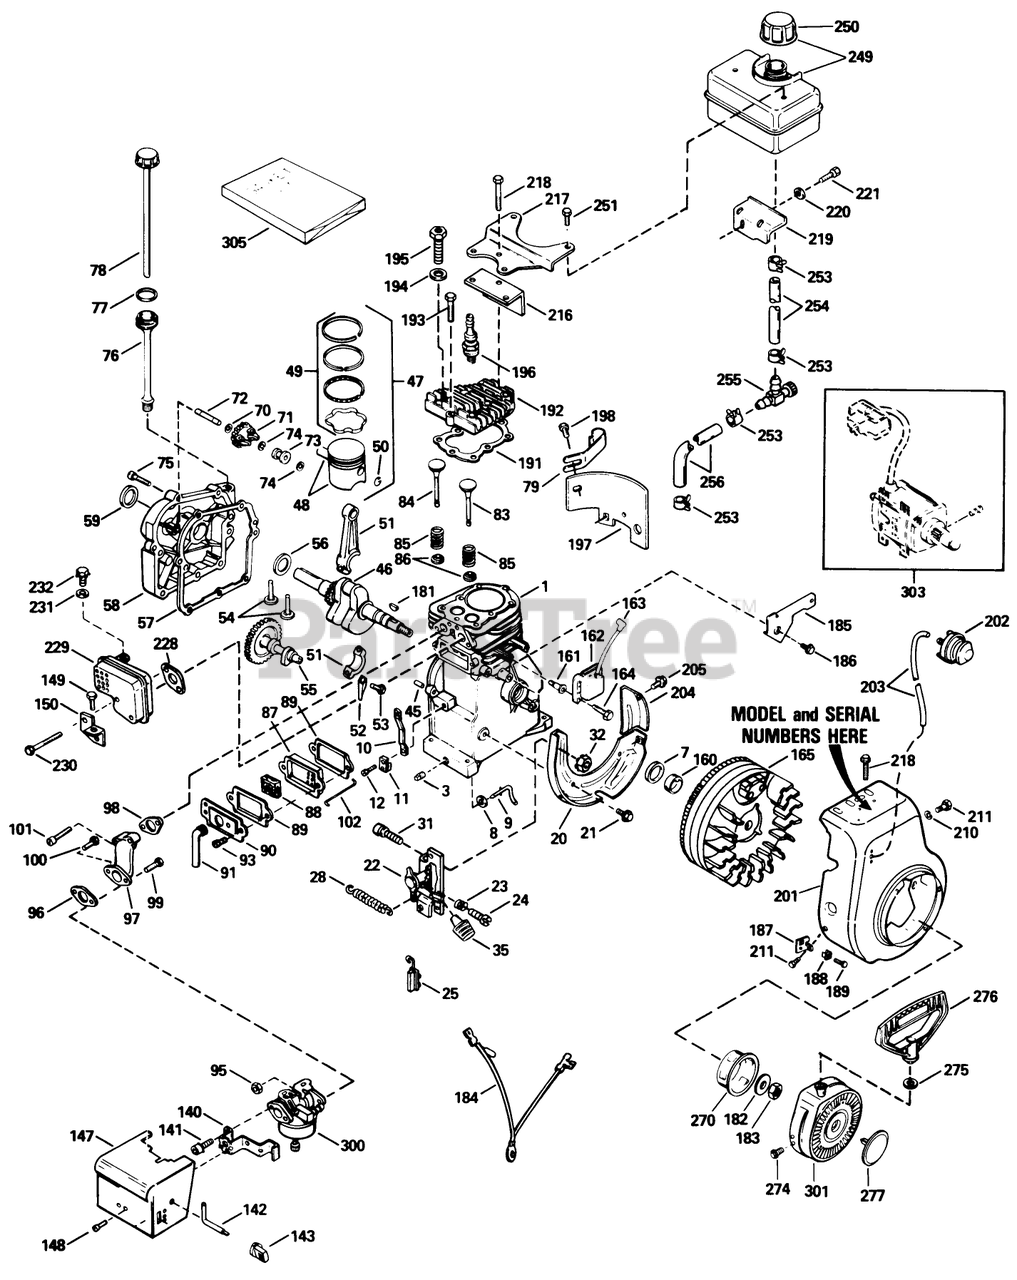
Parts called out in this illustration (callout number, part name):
1	Cylinder Assembly (Incl. Ref. #3, 7 45)
3	Plug-Drain, Oil (SQH 1/4-18)
7	Seal-Oil
8	Washer-Flat
9	Rod-Governor
10	Lever-Governor
11	Clamp-Lever, Governor
12	Screw
20	Baffle-Blower Housing
21	Screw (1/4-20x19/32)
22	Control Assembly, Speed (Incl. Ref. #155 thru 158 160)
23	Spring-Compression
24	Screw
25	Terminal
28	Spring-Extension
31	Screw
32	Nut-Lock
35	Knob-Control
45	Pin-Dowel
46	Crankshaft ASM
47	Piston, Pin Ring Assy., (Incl. Ref. #15 16) (Std.)
47	Piston, Pin Ring Assy., (Incl. Ref. #15 16) (.010 Oversize)
47	Piston, Pin Ring Assy., (Incl. Ref. #15 16) (.020 Oversize)
48	Piston Pin Assy. (Incl. Ref. #16) (Std.)
48	Piston Pin Assy., (Incl. Ref. #16) (.010 Oversize)
48	Piston Pin Assy. (Incl. Ref. #16) (.020 Oversize)
49	Ring Set-Piston Std.
49	Ring Set-Piston .010 oversize
49	Ring Set-Piston .020 oversize
50	Ring-Retaining, Piston Pin
51	Rod Assembly, Connecting (Incl. Nos. 17 18)
52	Dipper-Oil
53	Bolt-Rod, Connecting
54	Lifter-Valve
55	Camshaft
56	Washer-Thrust
57	Gasket-Cover, Cylinder
58	Cover-Cylinder (Incl. Ref. #59 72)
59	Seal-Oil
70	Washer
71	Governor Gear ASM
72	Shaft-Governor
73	Spool-Governor
74	Ring-Retaining
75	Screw (1/4-20 x 1-1/4)
76	Tube-Fill, Oil
77	O-Ring
78	Dipstick
79	Clip-Tube, Fill
83	Valve, Exhaust (Std.)(Incl. No. 40)
83	Valve, Intake (1/32" oversize)(Incl. No. 40)
84	Valve-Intake Standard (Incl. Ref. #151)
84	Valve-Intake 1/32" oversize (Incl. Ref. #151)
85	Spring-Valve
86	Cap-Valve, Spring
87	Body-Breather
88	Element-Breather
89	Gasket-Cover, Valve
90	Cover-Breather
91	Tube-Breather
93	Screw
95	Nut and Lock Washer (1/4-28)
96	Gasket
97	Pipe-Intake
98	Gasket-Intake
100	Screw (1/4-28 x 1-11/16)
101	Screw (1/4-20 x 1-19/32)
102	Link-Governor to Throttle
140	Bracket-Choke
141	Screw (10-32 x 1/2)
142	Rod-Choke
143	Knob-Control
147	Cover-Carburetor
148	Screw (8-32 X 5/16)
149	Screw (10-24 x 3/8)
150	Bracket-Cover, Carburetor
160	Spacer
162	Solid State
163	Cover-Spark Plug
164	Screw
165	CLAMP
181	Key-Flywheel
182	Washer-Belleville
183	Nut-Flywheel
184	Wire-Ground
185	Bracket-Hold Down
186	Screw (10-24 x 9/16)
187	Bracket
188	Grommet
189	Screw (8-32 x 3/8)
191	Gasket-Cylinder Head
192	Head-Cylinder (Incl. Ref. #218)
193	Screw (5/16-18x1-1/2)
194	Washer-Flat
195	Screw ( 5/16-18 x 1-1/2)
196	Spark Plug-Resistor (R J19 L M)
197	Extension-Blower
198	Screw
201	Housing-Blower
202	Primer-Asm
203	Line-Primer
204	Baffle-Extension
205	Screw-Hex Washer Hd.
210	Washer
211	Screw
216	Baffle-Heat
217	Plate-Fuel Tank
218	Screw (5/16-18 X 2)
219	Bracket-Fuel Tank
220	Washer
221	Screw Assembly
228	Gasket-Exhaust
229	Muffler
230	Screw-Fil. Hd.
231	Washer
232	Screw
249	Tank Assembly-Fuel (Incl. Ref. #250 253)
250	Cap-Fuel
251	Screw (1/4-15x7/8)
253	Clamp-Line, Fuel
254	Line-Fuel (8.62)
255	Valve-Shut Off
256	Line-Fuel
270	Cup-Starter
274	Screw, Hex Hd.
275	Washer
276	Handle-Starter, Mitten Grip
277	Plug Starter
300	Carburetor (Incl. Ref. #96)
301	Rewind Starter
303	Electric Starter Kit 33290C (Optional) Sold as Accessory
305	Gasket Set (Incl.Items Marked *)
